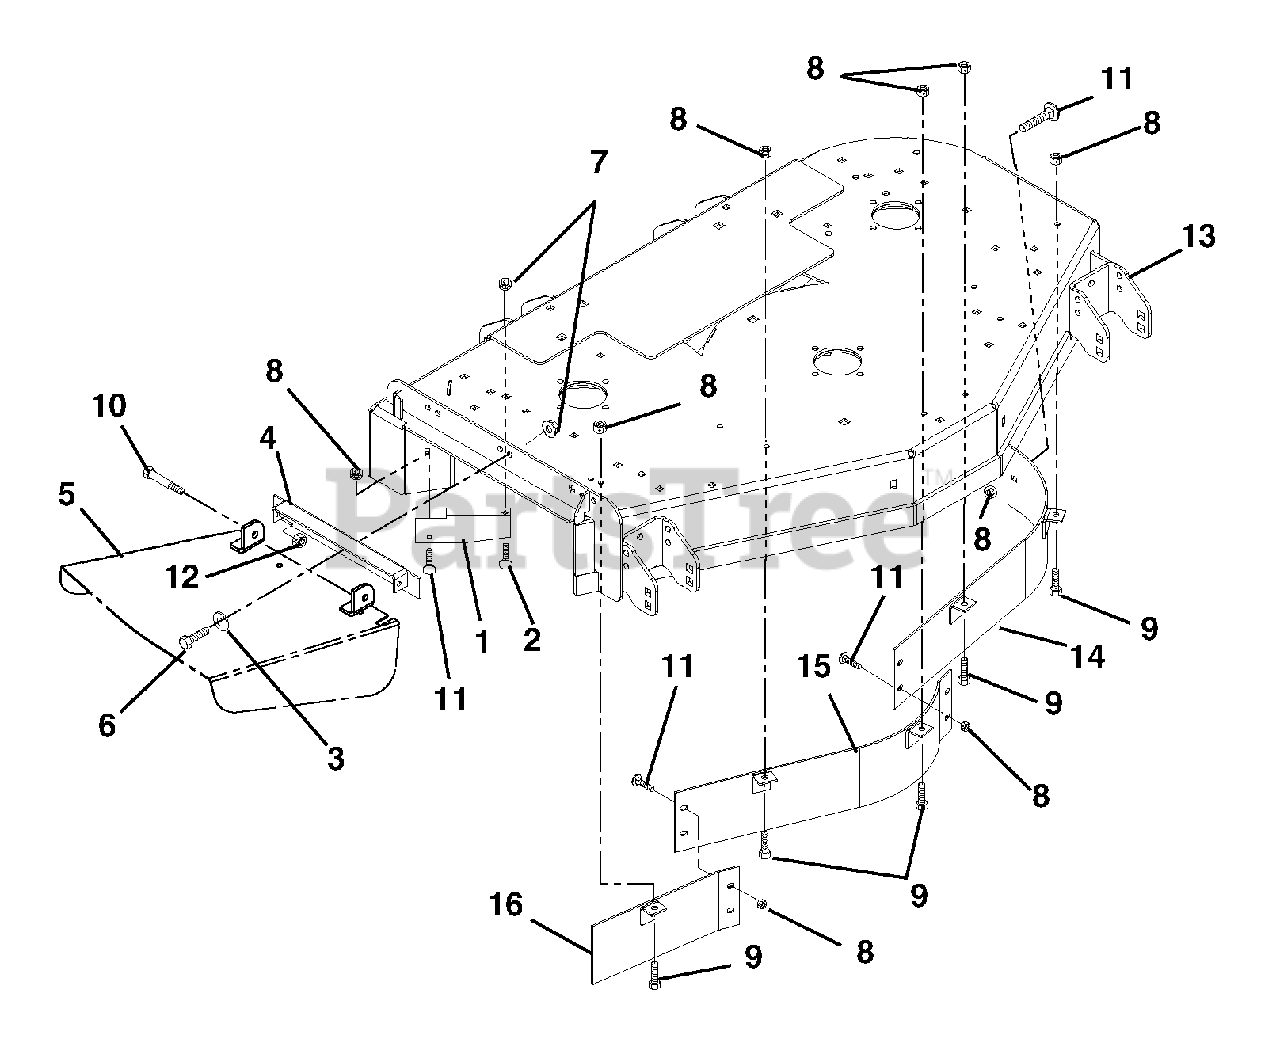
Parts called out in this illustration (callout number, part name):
1	Deflector, 52" (044, 054)
1	Deflector, 60" (051, 055)
1	Deflector (042, 043, 310, 311)
2	Bolt, Round Head Square Neck .38-16 x 1.00 Grade 5
3	Washer, Flat Steel .38 x .875 x .083 (042, 043, 044, 054, 310, 311)
4	Weldment Discharge Chute Bracket (042, 043, 044, 054, 310, 311)
4	Weldment Discharge Chute Bracket (051, 055)
5	Chute, Discharge (042, 043, 044, 054, 310, 311)
5	Chute, Discharge (051, 055)
6	Bolt, Hex .38-16 x 1.00 Grade 5
7	Nut, Locking Top Flange .38-16
8	Nut, Locking Top Flange .31-18
9	Bolt, Hex .31-18 x .75 Grade 5
10	Bolt, Shoulder .38-16 x .50 Socket Head
11	Bolt, Round Head Square Neck .31-18 x .75 Grade 5
12	Nut, Locking Center .38-16
13	Weldment, 52" Mower Deck (044, 054)
13	Weldment, 60" Mower Deck (051, 055)
13	Weldment, 44" Mower Deck Float (042, 310)
13	Weldment, 48" Mower Deck (043, 311)
14	Weldment, Upper Baffle Left - 52" (044, 054)
14	Weldment, Upper Baffle Left - 60" (051, 055)
14	Weldment, Baffle Left Front - 44" (042, 310)
14	Weldment, Upper Baffle Left - 48" (043, 311)
15	Weldment, Baffle Center Front - 52" (044, 054)
15	Weldment, Baffle Center Front - 60" (051, 055)
15	Weldment, Baffle Center Front - 44" (042, 310)
15	Weldment, Upper Baffle Center-48" (043, 311)
16	Weldment, Baffle Right Front - 52" (044, 054)
16	Weldment, Baffle Right Front - 60" (051, 055)
16	Weldment, Baffle Right Front - 44" (042, 310)
16	Weldment, Upper Baffle Right - 48" (043, 311)
